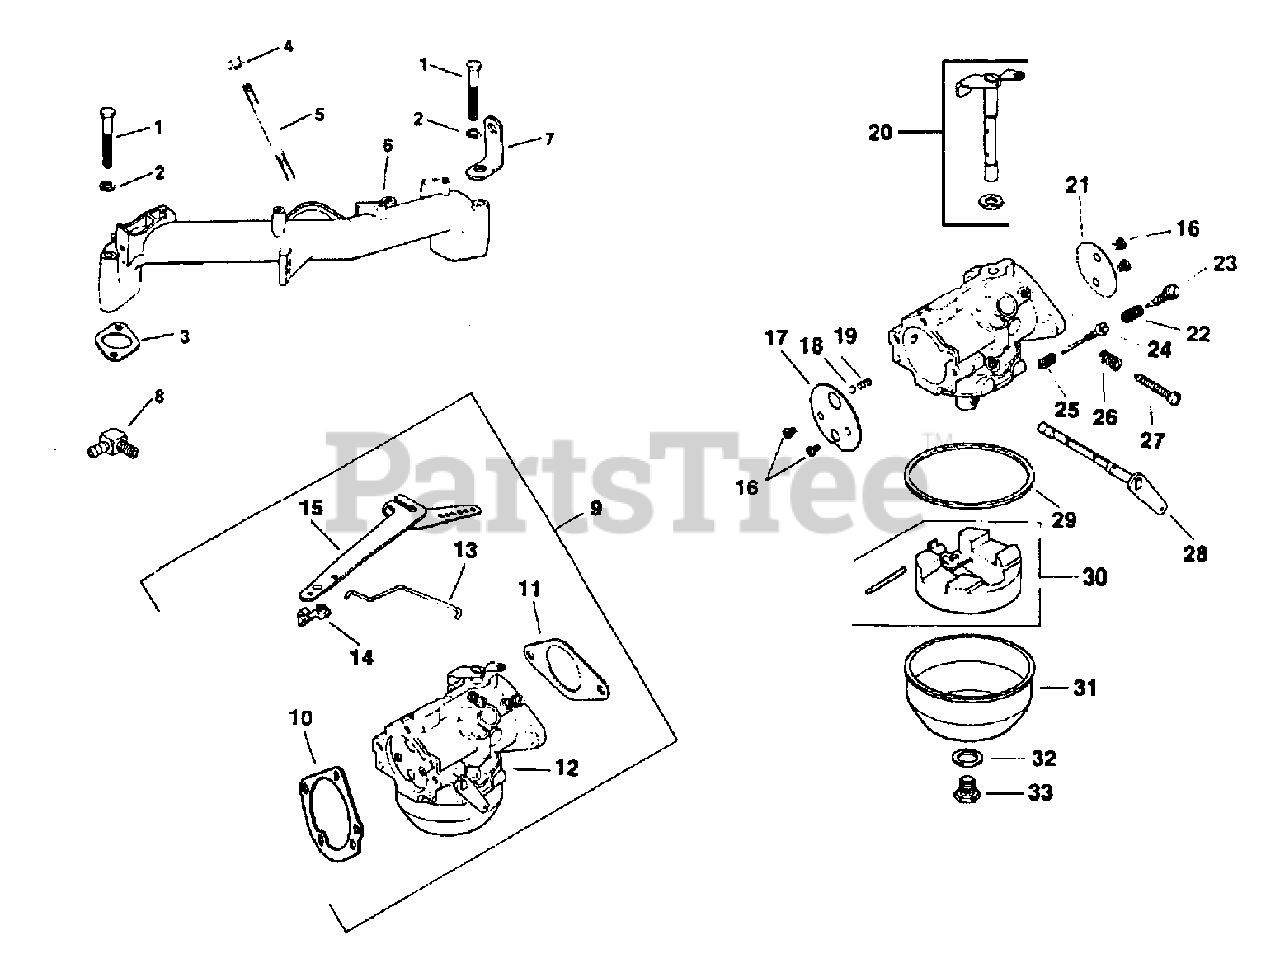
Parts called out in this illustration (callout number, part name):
1	SCREW
2	WASHER
3	GASKET, INTAKE
4	NUT
5	STUD
6	MANIFOLD, INTAKE
7	STRAP, LIFTING
8	CONNECTOR, HOSE
9	KIT
10	GASKET, ELBOW
11	GASKET
12	CARBURETOR ASSEMBLY
13	KIT, GOVERNOR LINKAGE
14	BUSHING
15	ARM
16	SCREW, THROTTLE PLATE
17	PLATE, CHOKE
18	BALL, CHOKE, FRICTION
19	SPRING, CHOKE, FRICTION
20	SHAFT
21	PLATE
22	THROTTLE
23	SPRING
24	NEEDLE
25	THROTTLE
26	SPRING
27	SCREW
28	LEVER
29	GASKET
30	KIT
31	BOWL
32	GASKET
33	SCREW
